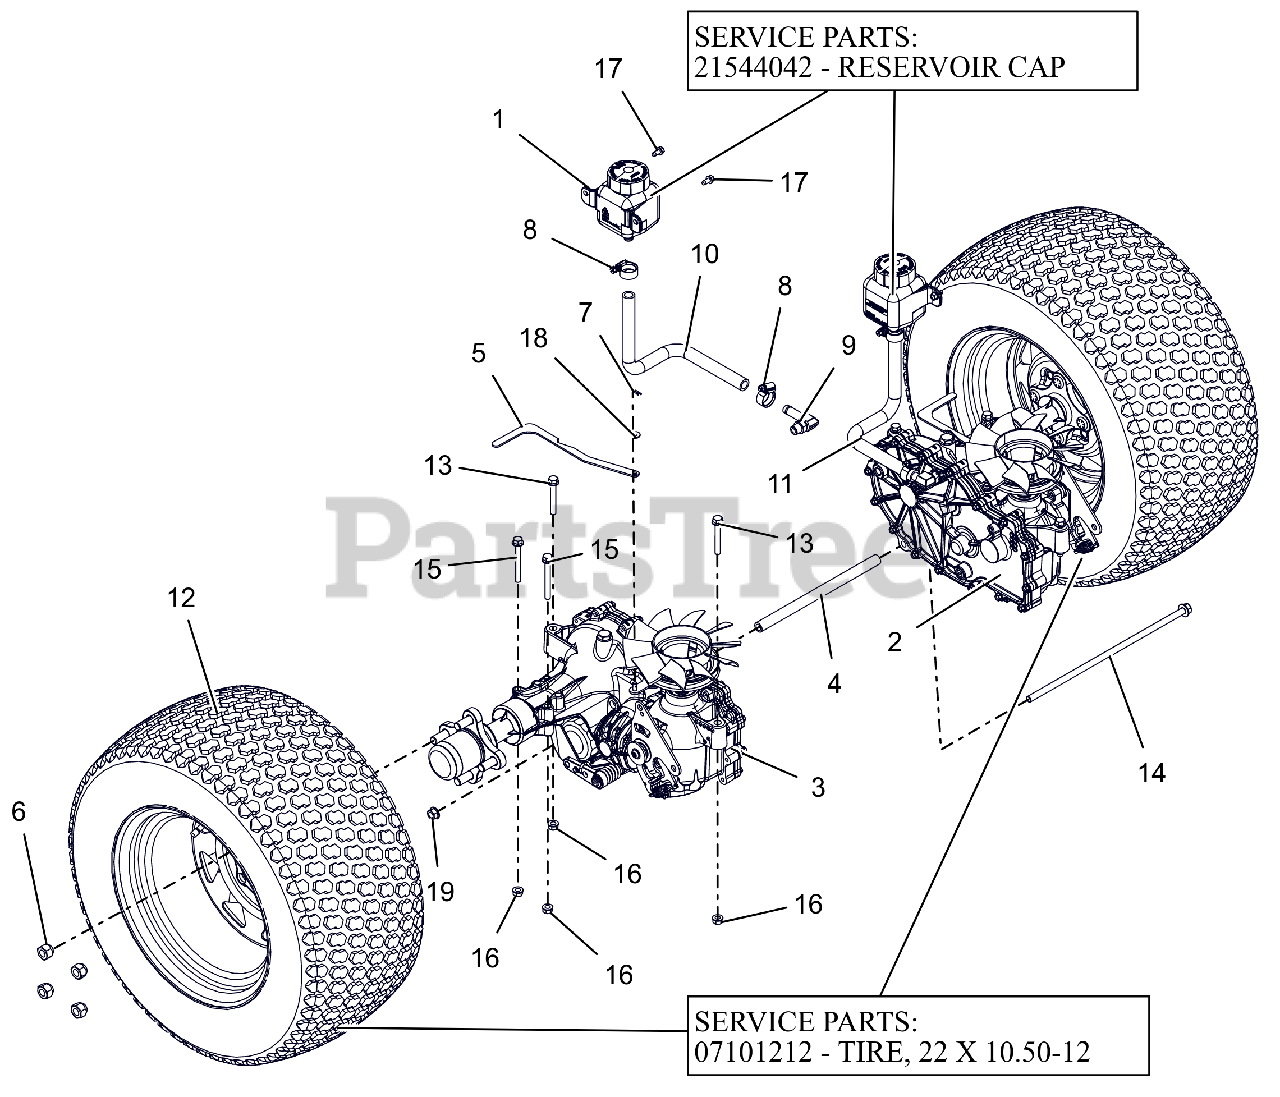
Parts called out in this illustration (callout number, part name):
1	TANK, EXPANSION
1	CAP, HYDRO RESERVOIR REPLAC.
2	TRANSAXLE, ZT3100 LH
3	TRANSAXLE, ZT3100 RH
4	SPCR, TRANSAXLE .406 ID X .630 OD X 9.95LG (BLACK)
5	BRKT, VALVE DUM
6	NUT, WHEEL .50-20 ZCC
7	PIN, HAIR #225 .072X1.09
8	CLAMP,.88 DIA. HOSE
9	FITTING, HYD (90 DEG)
10	HOSE, FORMED EXPANSION -HD RH
11	HOSE, FORMED EXPANSION -HD LH
12	ASM, WHL/TIRE 22X10.50-12 K500
12	TIRE, 22X10.50-12
13	BLT,HEX-FLG .31-18X2.25 G5 ZCC
14	BLT, HEX-FLG 0.375-16X13 GR5 ZC120
15	BLT,HEX-FLG .31-18X2.75 G5 ZCC
16	NUT,LK-CTR-FLG .31-18 GF ZCC
17	SCR-TAP .25-20X.50 HWH ZCC
18	WSHR,FLT .281X.625X.065 ZCC
19	NUT-LK-CTR-FLG .375-16 GF ZCC
